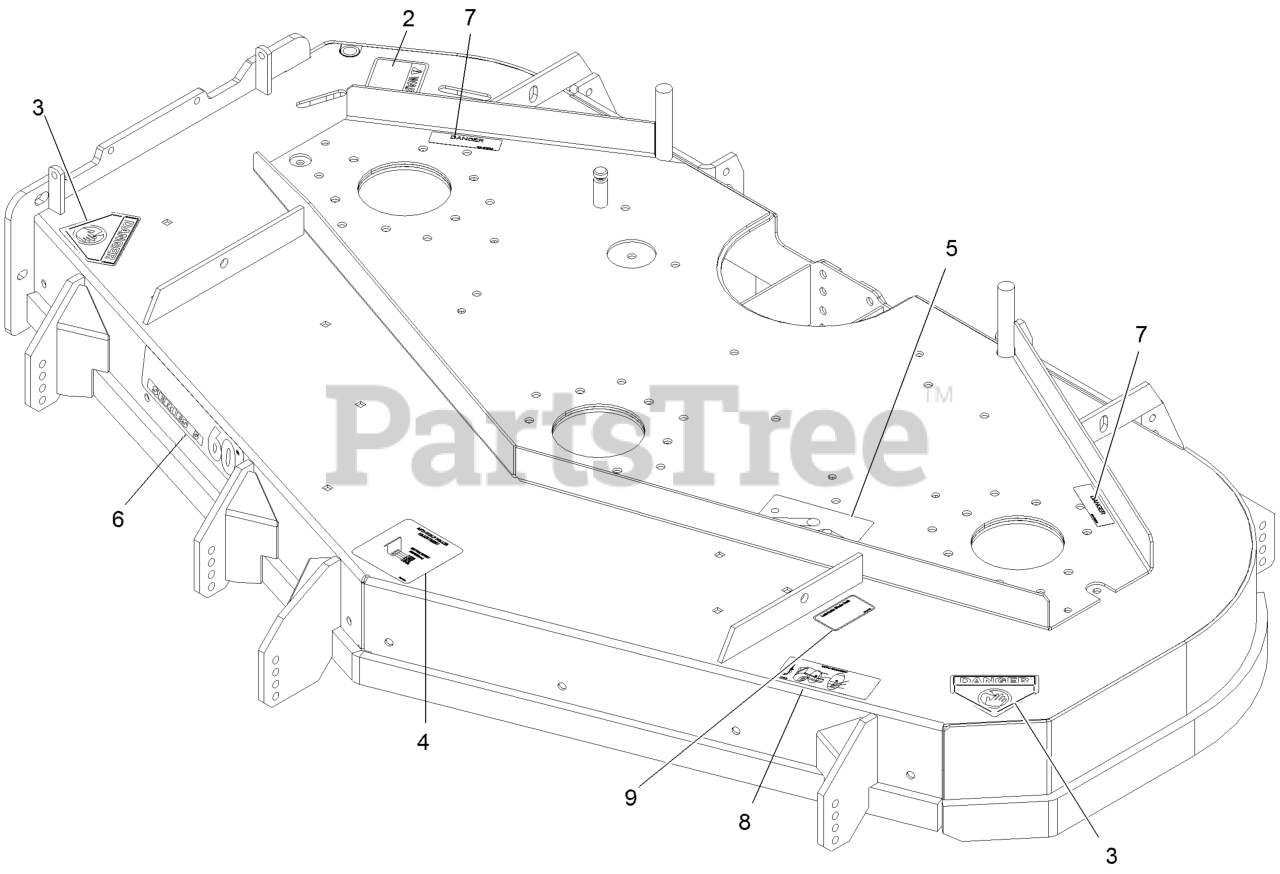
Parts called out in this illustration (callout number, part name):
2	DECAL-WARNING, DISCHARGE
3	DECAL-DANGER
4	DECAL,ANTISCALP
5	DECAL,BELT ROUTING
6	DECAL, SERIES 5 - 60
7	DECAL-COVER, MISSING
8	DECAL,BAFFLE ADJUSTMENT
9	DECAL,BOLT TORQUE
